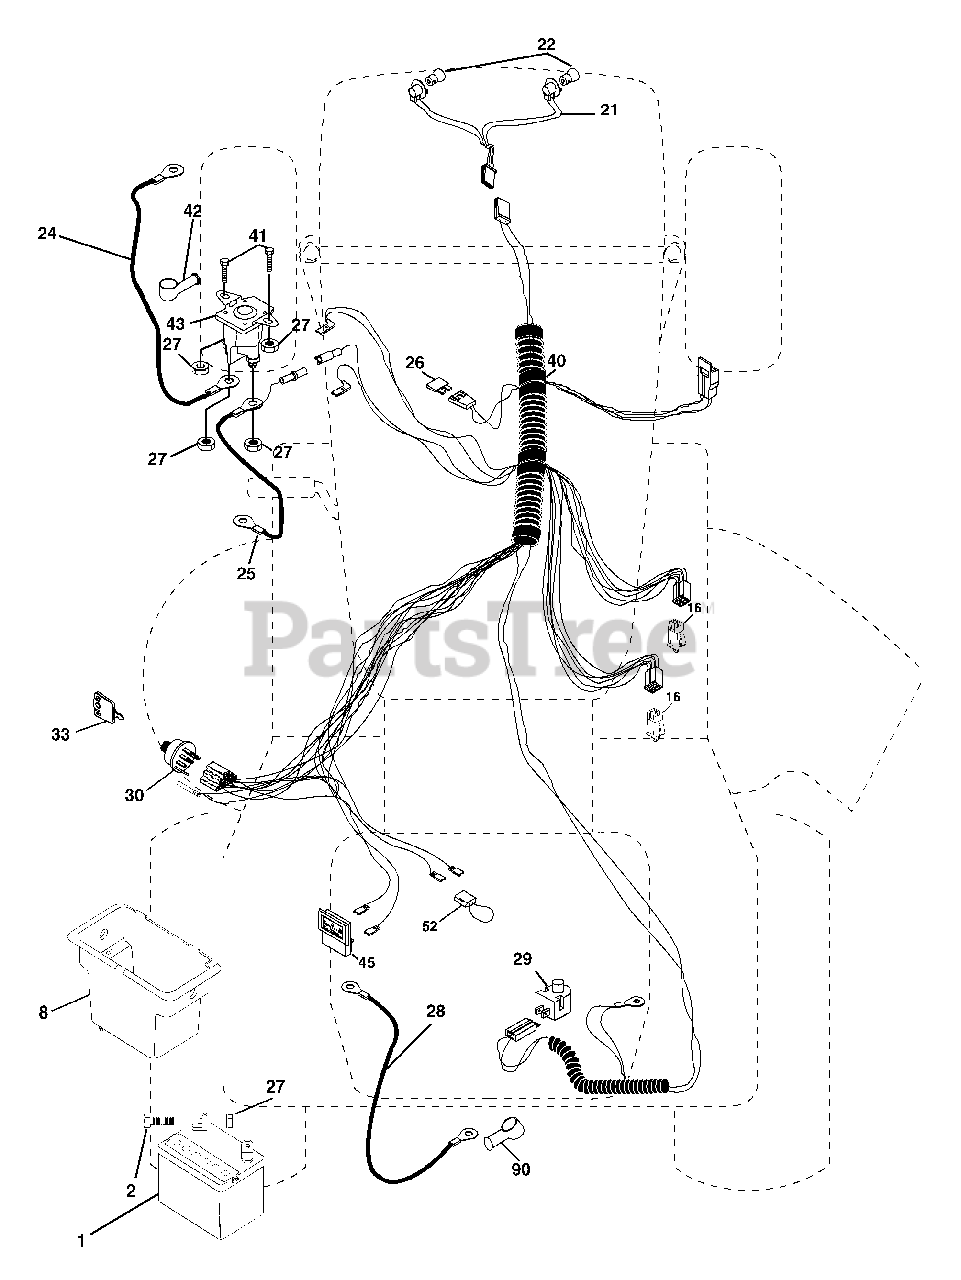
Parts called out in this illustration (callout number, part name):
1	Battery 12 Volt 25 Amp
2	Bolt Hex Hd 1/4-20 unc x 3/4
8	Box Battery
16	Switch Interlock Push -In
21	Harness Asm Light W/4152J
22	Bulb Light #1156
24	Cable Battery 6 Ga. 11"red
25	Cable Battery 6 Ga. w/16 wire,red
26	Fuse 20 AMP
27	Nut Keps Hex 1/4-20 unc
28	Cable Ground 6 Ga. 12" black
29	Switch Plunger Nc Gray
30	Switch Ign
33	Key Ign
40	Harness Ign
41	Bolt Blk Fin Hex 1/4-20 x 1/2
42	Cover Terminal Red
43	Solenoid
45	Ammeter
52	Protection Wire Loop
90	Cover Terminal
